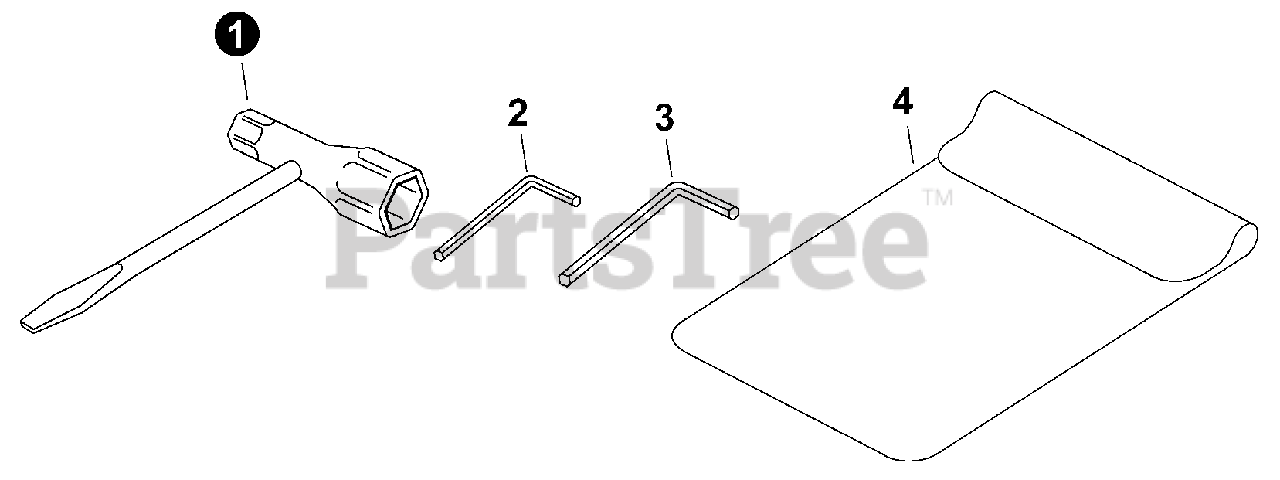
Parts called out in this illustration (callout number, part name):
1	T-WRENCH 16×13
2	WRENCH, ALLEN 4 MM
3	WRENCH, ALLEN 5 MM
4	BAG, TOOL
